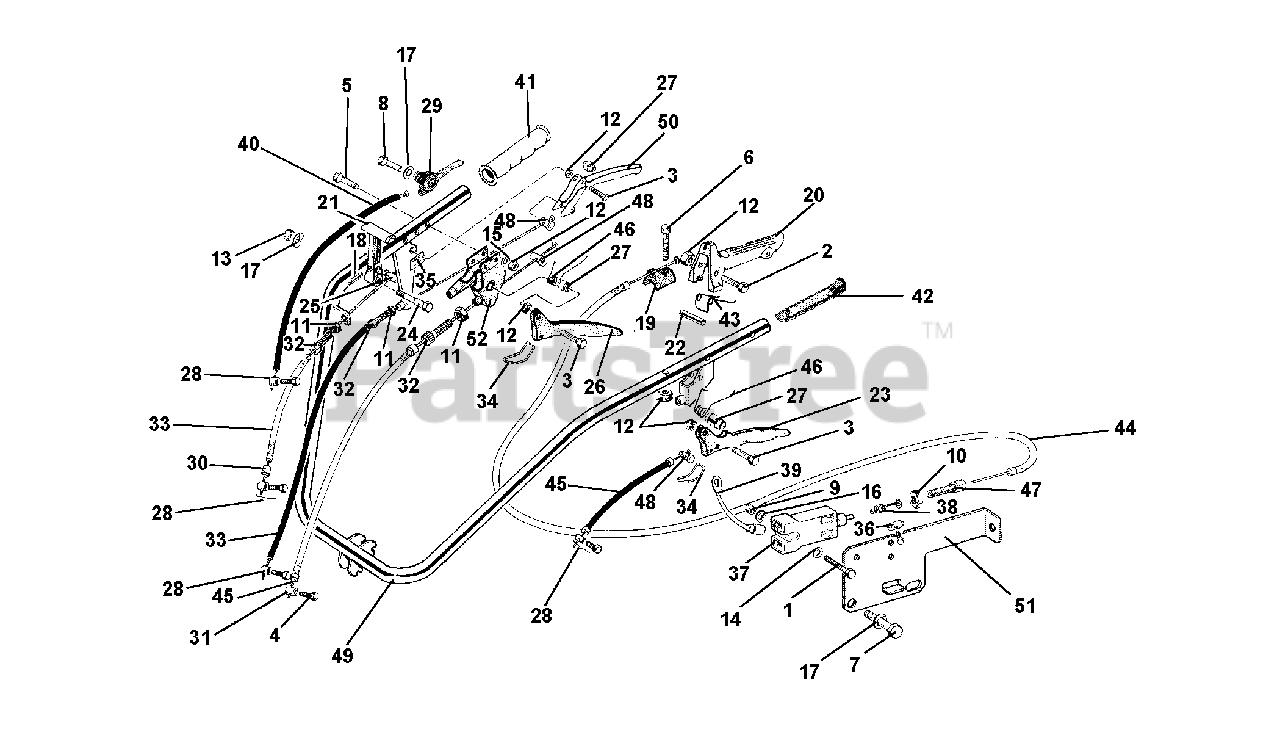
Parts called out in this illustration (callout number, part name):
1	SCREW TE M4 X 25
2	SCREW TE M6 X 45
3	SCREW M6 X 25
4	SCREW TE M6 X 16
5	SCREW M6 X 40
6	SCREW M6 X 35
7	SCREW M8 X 12
8	SCREW TE M8 X 40
12	NUT, SELF LOCKING M6
13	NUT, SELF LOCKING M8
14	FLAT WASHER 4.3
15	WASHER, LOCK 6.4
16	LOCK WASHER B 4.3
17	WASHER, LOCK 8.4
18	PIN, LOCKING 4 X 20
19	SHEATH STOP OF MOTOR STOP
20	MOTOR STOP LEVER
21	LEVER DIFFERENTIAL LOCKING
22	LEVER STOP FOR MOTOR STOP
23	CLUTCH LEVER
25	DRILLED PIN
27	LEVER SPACER
28	CLAMP, CABLE
29	LEVER, ACCELERATOR
30	END, SHEATH
31	PIN, CABLE CLAMP
32	SCREW, ADJUSTING M8
33	CABLE & SHEATH, CLUTCH
35	REVERSER DECAL
36	CABLE CLAMP
37	STOP SWITCH
38	SWITCH SPRING
39	SWITCH CABLES
40	WIRE, SHEATH 1850 GAS
43	MOTOR STOP LEVER SPRING
44	SHEATH CABLE
45	SHEATH CABLE
46	LEVER SPRING
47	ADJUSTING SCREW
50	REVERSE SPEED LEVER
51	SUPPORT FOR ACME STOP SWITCH
52	COUPLING FOR DOUBLE LEVER
